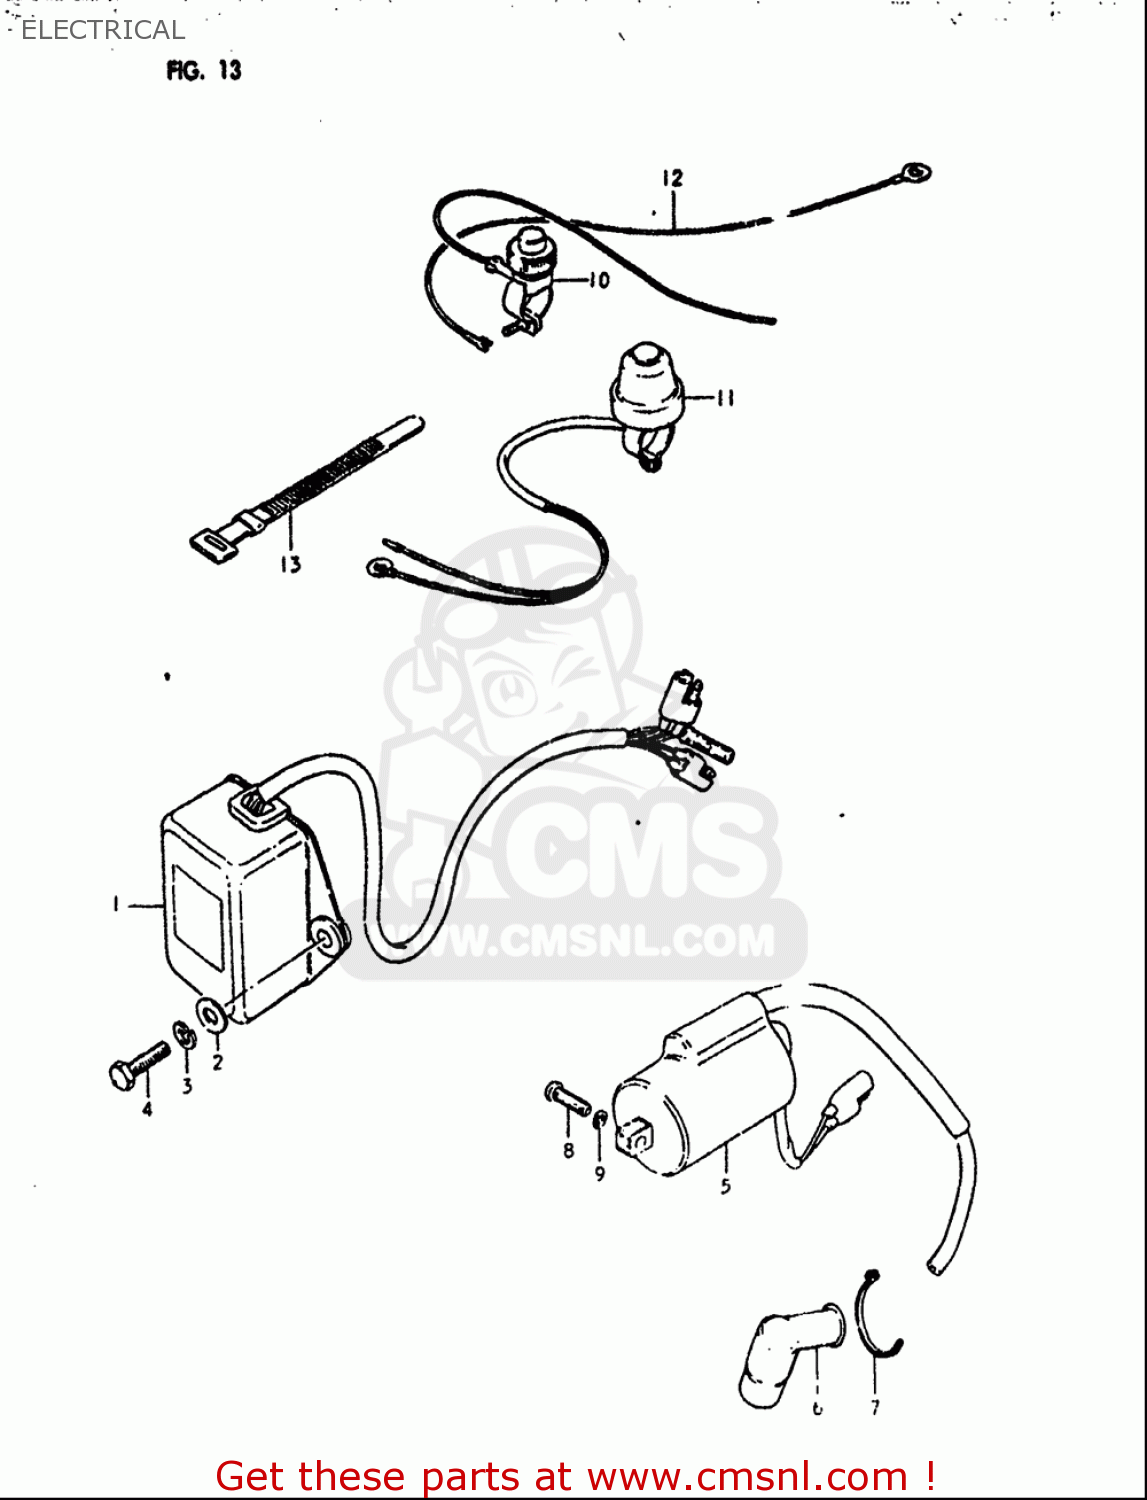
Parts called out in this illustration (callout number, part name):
1	CDI UNIT ASSEMBLY
2	WASHER(6.5X16X1.2)
3	WASHER,LOCK
4	BOLT
5	COIL ASSY,IGNITION
6	CAP,SPARK PLUG
7	CLAMP
8	SCREW
9	WASHER,LOCK
10	SWITCH ASSY,ENGINE STOP
11	SWITCH ASSY,ENGINE STOP
13	CLAMP(L:120)
